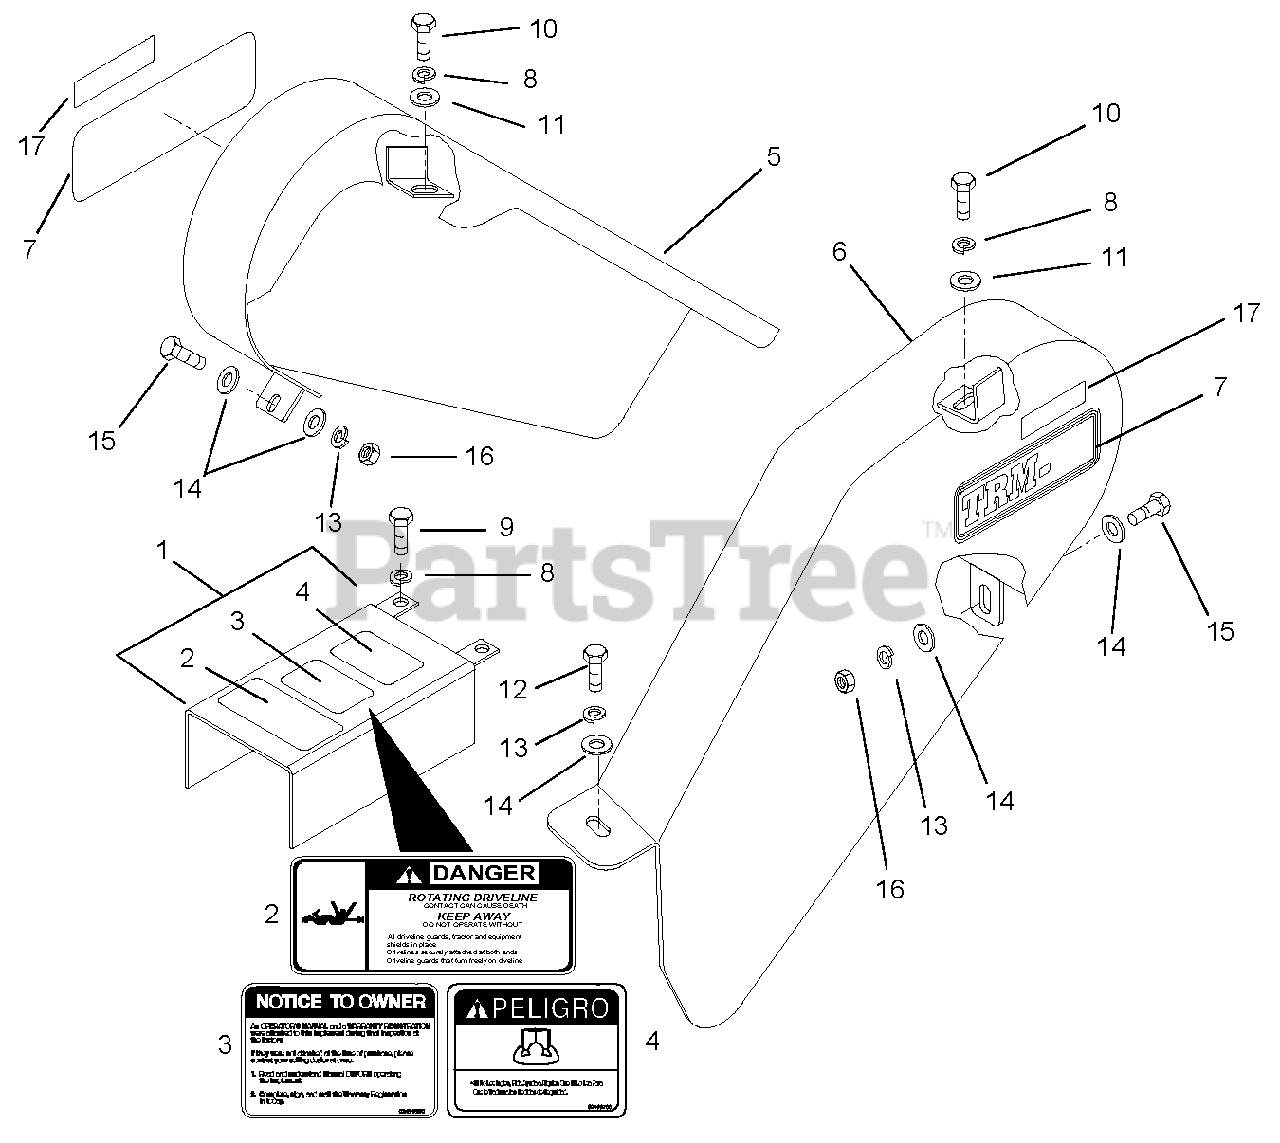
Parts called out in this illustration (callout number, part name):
1	Guard Assembly, Driveshaft
2	Decal, Danger
3	Decal, Notice to Owner
4	Decal, Danger
5	Weldment, Right Hand Drive Guard
6	Weldment, Left Hand Drive Guard
7	Decal, Model TRM-5138
7	Decal, Model TRM-7192
8	Washer, Lock .50
9	Cap Screw, Hex Head .50-13 x .75
10	Cap Screw, Hex Head.50-13 x 1
11	Washer, Flat .50
12	Cap Screw, Hex Head .375-16 x .75
13	Washer, Lock .375
14	Washer, Flat .375
15	Cap Screw, Hex Head .375-16 x 1
16	Nut, Hex .375-16 CP
17	Decal, Gravely 9.5"
